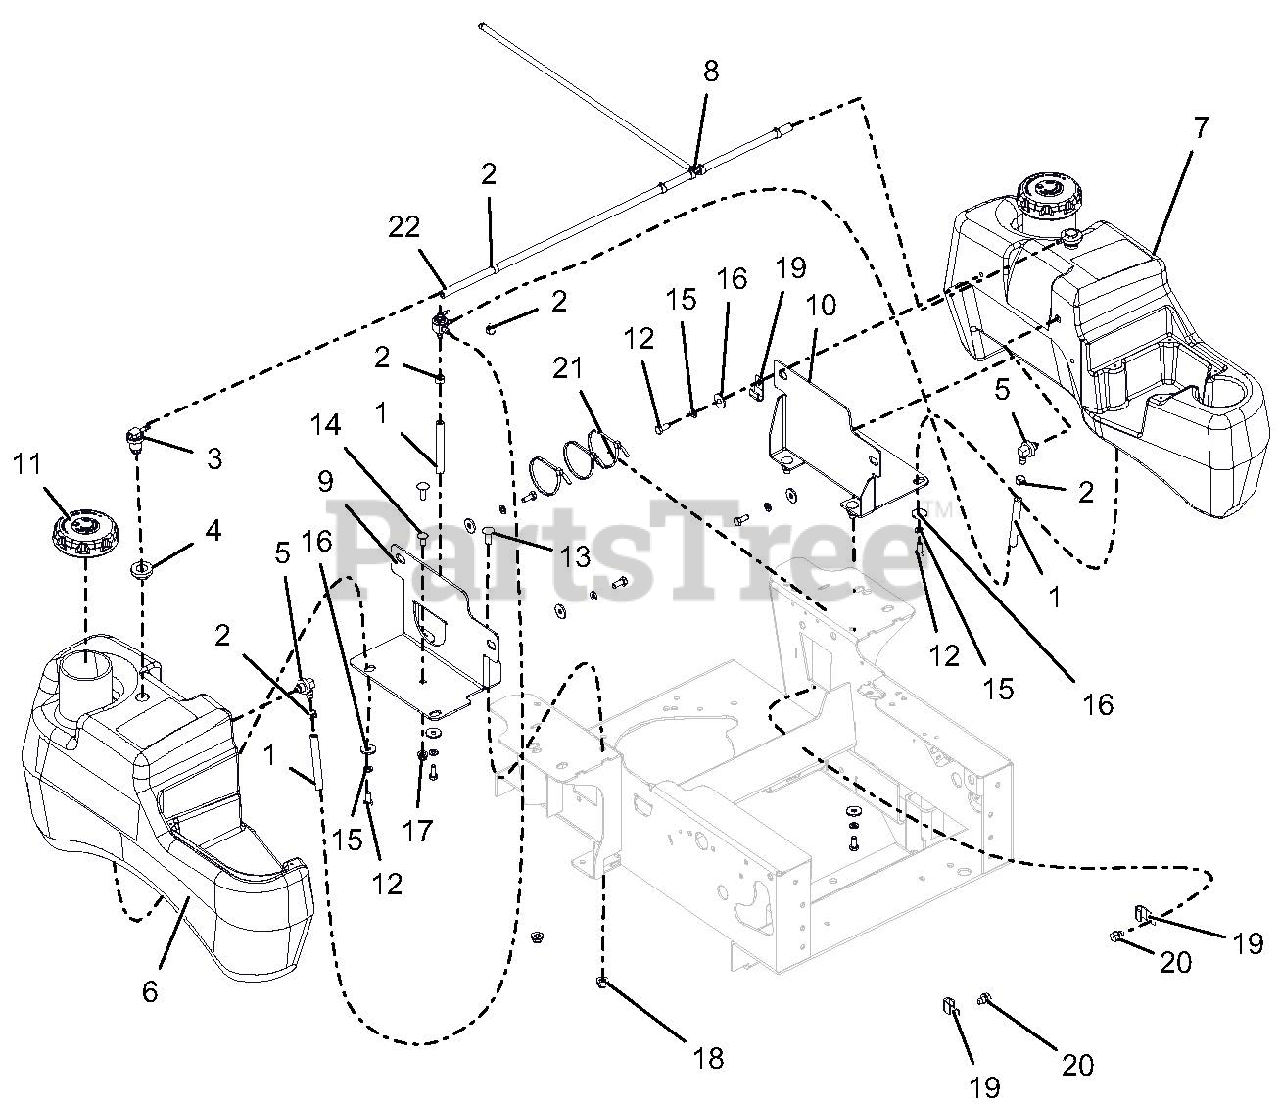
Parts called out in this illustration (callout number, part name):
1	.25 LOW-PERM GAS HOSE
2	CLAMP, FUEL LINE
3	VALVE, 2-WAY
4	GROMMET, REMOTE VENT NITRILE
5	ASS'Y, SMALL/ MED TANK FUEL PICK-UP
6	TANK, GAS - RH MEDIUM GRAVELY
7	TANK, GAS - LH MEDIUM GRAVELY
8	ASM, PT100 KAW FUEL LINE
9	BRKT, RH MEDIUM FUEL TANK MTG (RED)
10	BRKT, RH MEDIUM FUEL TANK MTG (RED)
11	CAP, FUEL VENT-IN AUTOLOCK
12	BLT-HEX .31-18X.75 GR5 YWZC
13	BLT-RDHDSHSQNK.38-16X1.0 G5YZ
14	BLT-RDHDSQNK .31-18X.75 G5 YWZC
15	WSHR-LK .31X.078 REG YWZC
16	WSHR-FL-STL .328X1.00X.094 YWZC
17	NUT-LK-NYL-FLG .31-18 YWZC
18	NUT-LK-NYL-FLG .38-16 YWZC
19	CLAMP, J
20	SCR-TAP .38-16X.50 HWH TR YWZ
21	CABLE, TIE 5.50 LG
22	VALVE, FUEL
